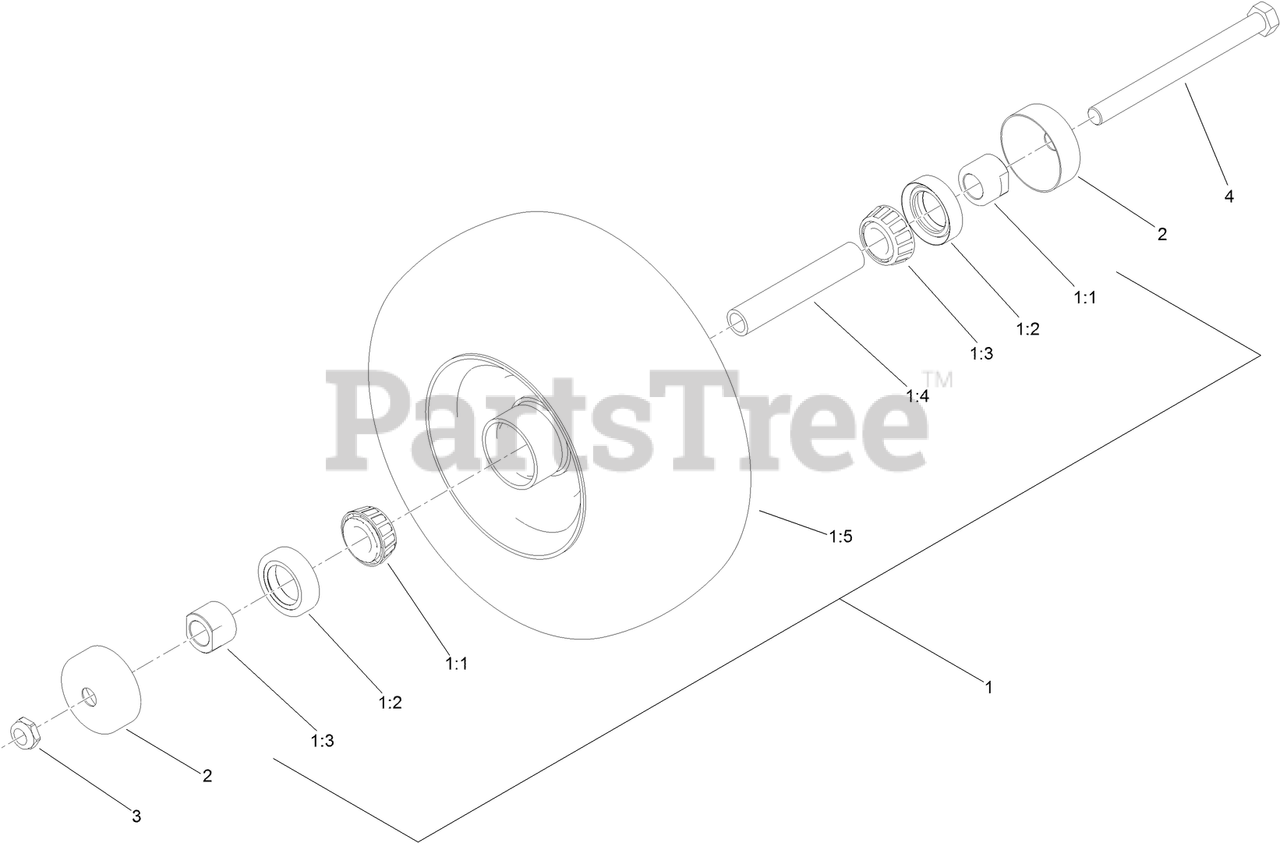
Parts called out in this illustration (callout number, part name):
1	WHEEL AND BEARING ASM
1:1	BEARING-CONE, TAPER
1:2	SEAL-CASTER
1:3	SPACER-NUT
1:4	AXLE-CASTER
1:5	WHEEL AND TIRE ASM
2	GUARD-SEAL
3	NUT-LOCK, NI
4	SCREW-HH
